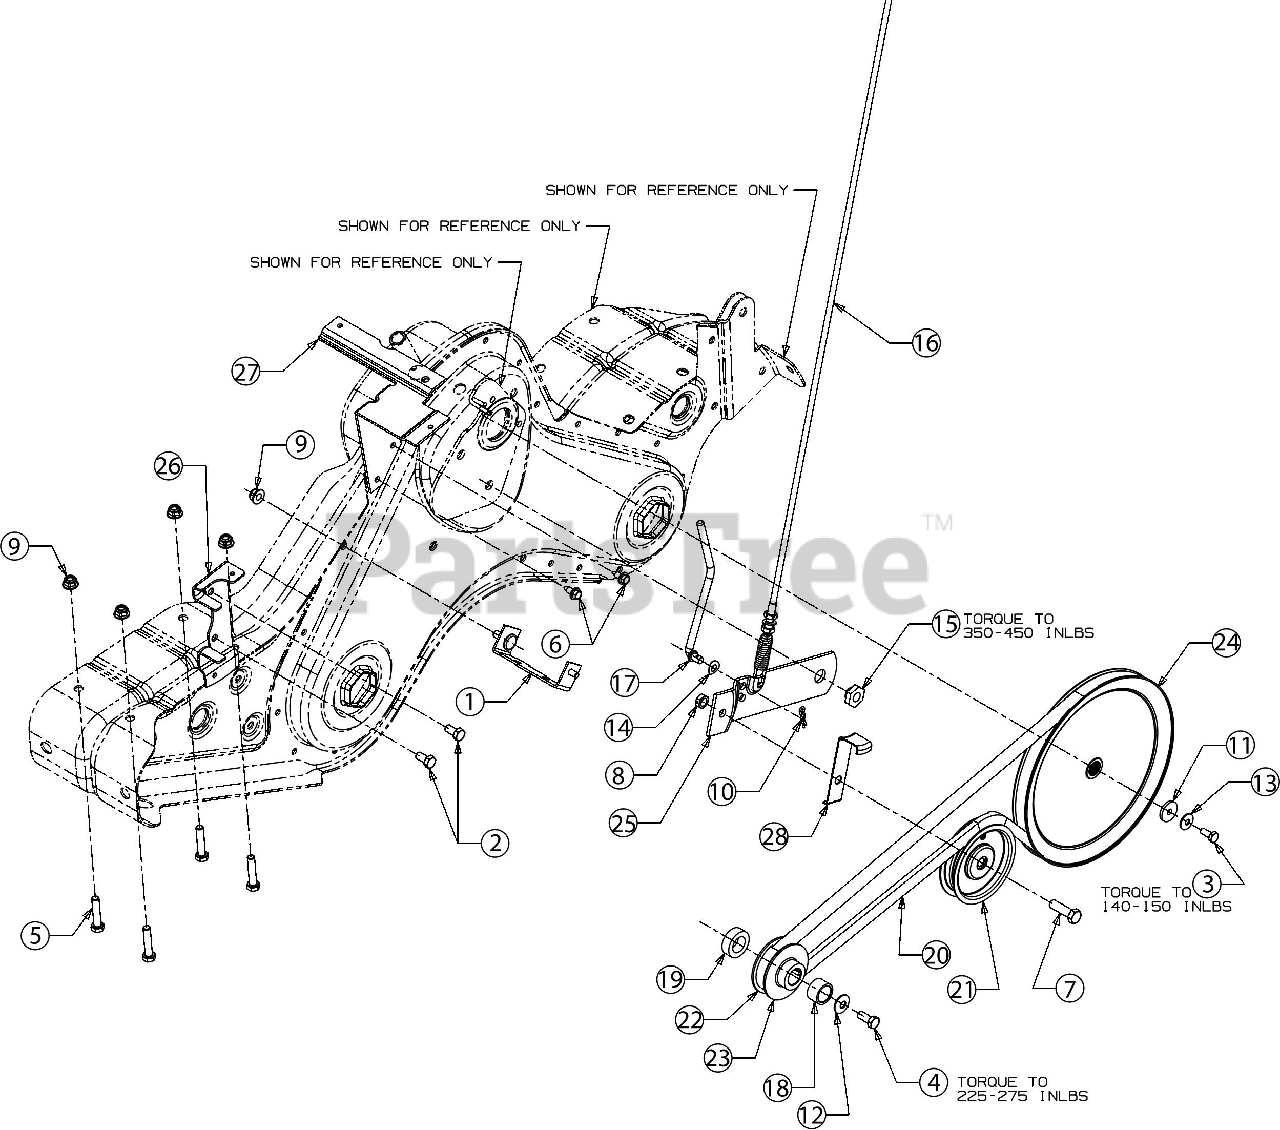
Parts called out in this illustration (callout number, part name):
1	BELT COVER BRACKET ASSEMBLY
1	WELD BOLT 5/16-18 X .875
2	HEX SCREW 5/16-24 X .62
3	BOLT 1/4-28 X .625 GR8
4	SCREW 5/16-24 X .750 GR5
5	SCREW 5/16-18 X 1.5 LG
6	SCREW 1/4-20X.625
7	SCREW 3/8-16 X 1.25 GR5
8	JAM LOCK NUT
9	FLANGE LOCK NUT 5/16-18
10	COTTER PIN .072 DIA
11	FLAT WASHER
12	BELL WASHER .337 X.867 X .057
13	SPRING WASHER BELL
14	SPRING WASHER .317 X .625 X .020
15	SHOULDER NUT
16	CLUTCH CABLE
17	IDLER PULLEY ROD
18	SPACER .77X.98X.57LG
20	BELT 1/2 X 58.16
21	IDLER PULLEY
22	ENGINE PULLEY INNER HALF
23	ENGINE PULLEY OUTER HALF
24	INPUT PULLEY
25	IDLER BRACKET
26	BELT KEEPER BRACKET
27	SHIFT COVER BRACKET
28	IDLER BELT KEEPER
